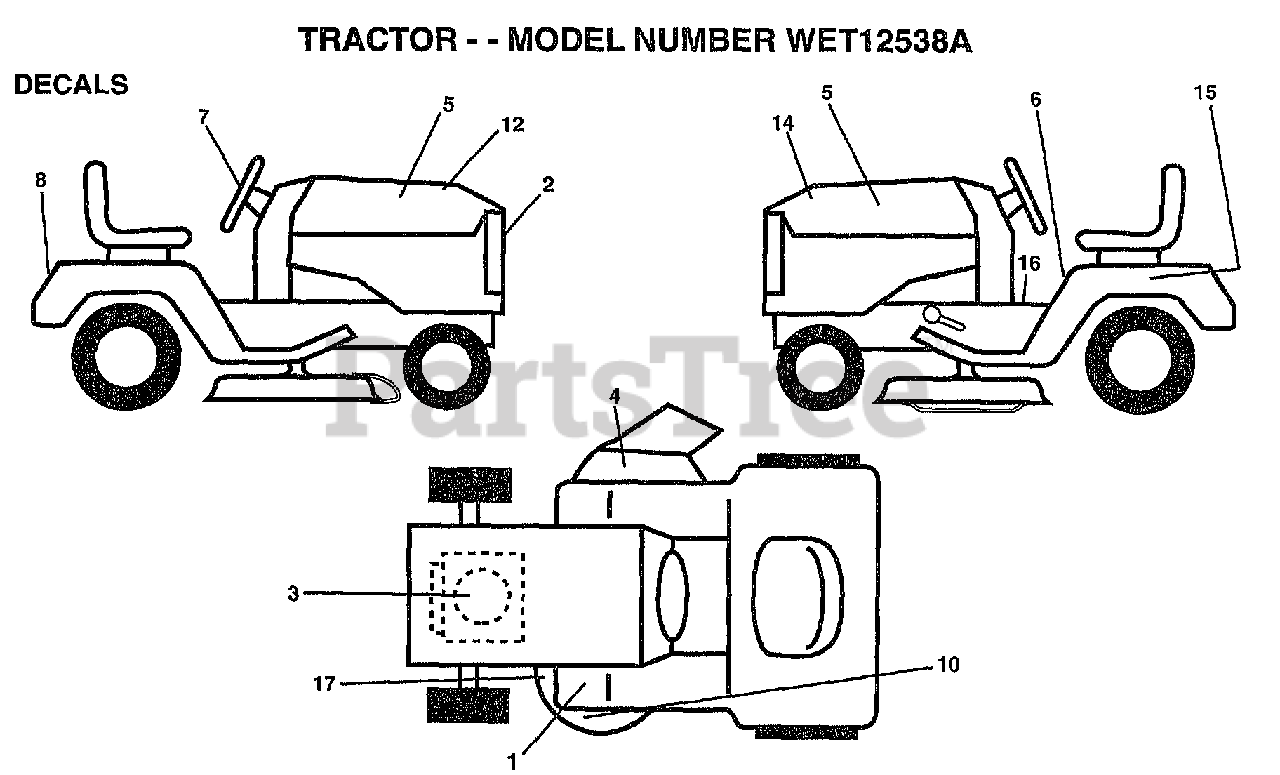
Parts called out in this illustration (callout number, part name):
1	DECAL T
2	DECAL, GRILLE LENS
4	"DECAL, WARNING"
5	DECAL
6	DECAL.CAUT.ENG/FR
7	DECAL, INS STRG WH
8	DECAL.FENDER.LOGO
10	DECAL, DECK GRASSEATER
12	DEECAL.HOOD.RH
14	DECAL.HOOD.LH
15	DECAL.BATRY.3-3908
16	"DECAL.OPER,SDL"
17	DECAL
